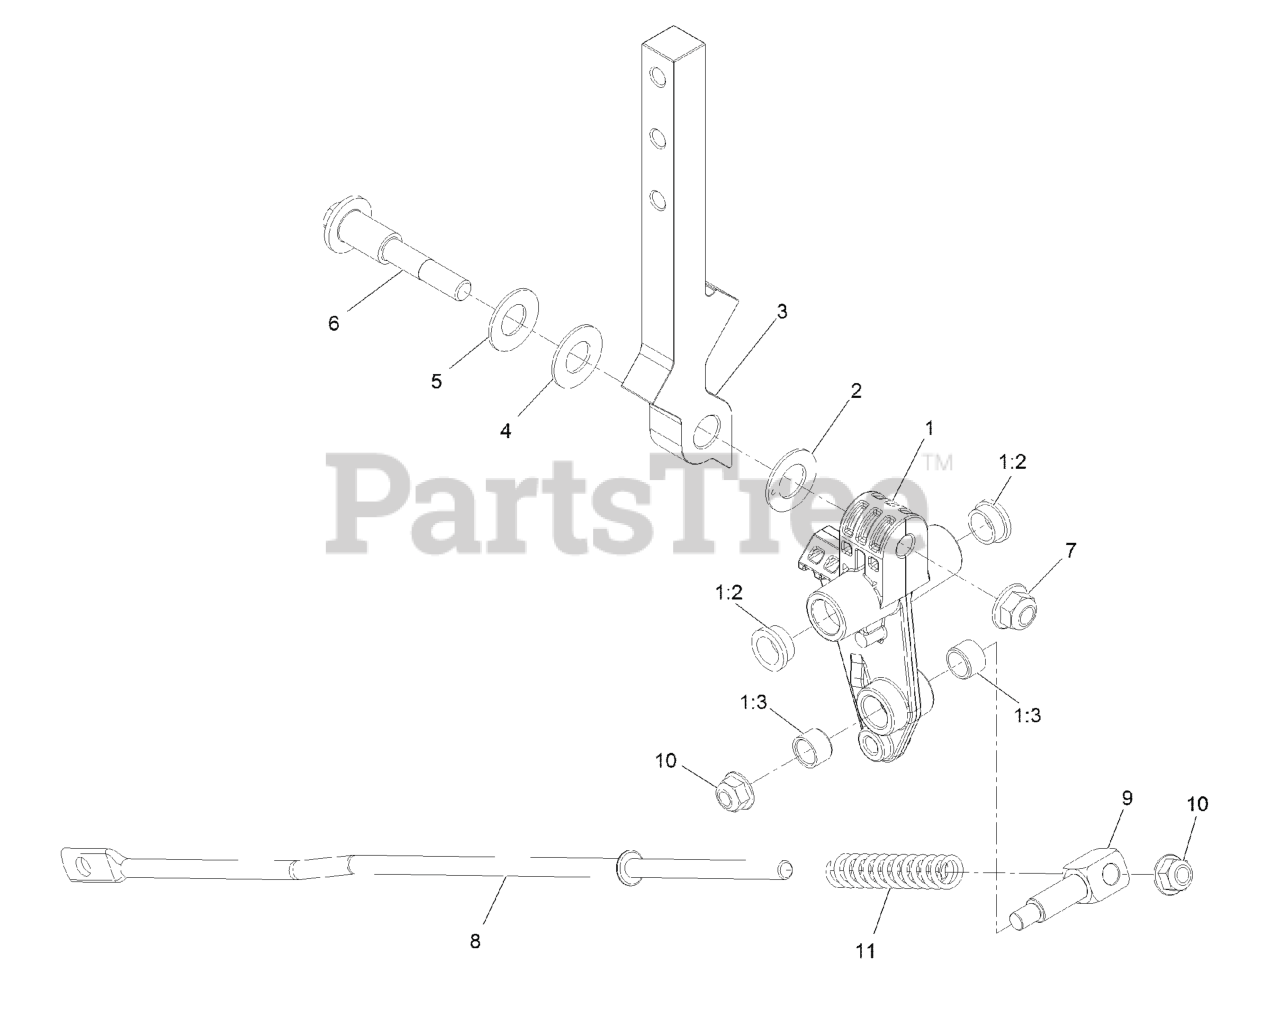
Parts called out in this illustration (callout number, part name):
1	CONTROL ARM ASM
1:2	BUSHING
1:3	BUSHING-SLEEVE
2	WASHER-FRICTION
3	ARM-CONTROL
5	WASHER-BELLEVILLE
6	BOLT-PIVOT
7	NUT-HF, NI
8	LINK-CONTROL
10	NUT-HF, NI
11	SPRING-RETURN, NEUTRAL
